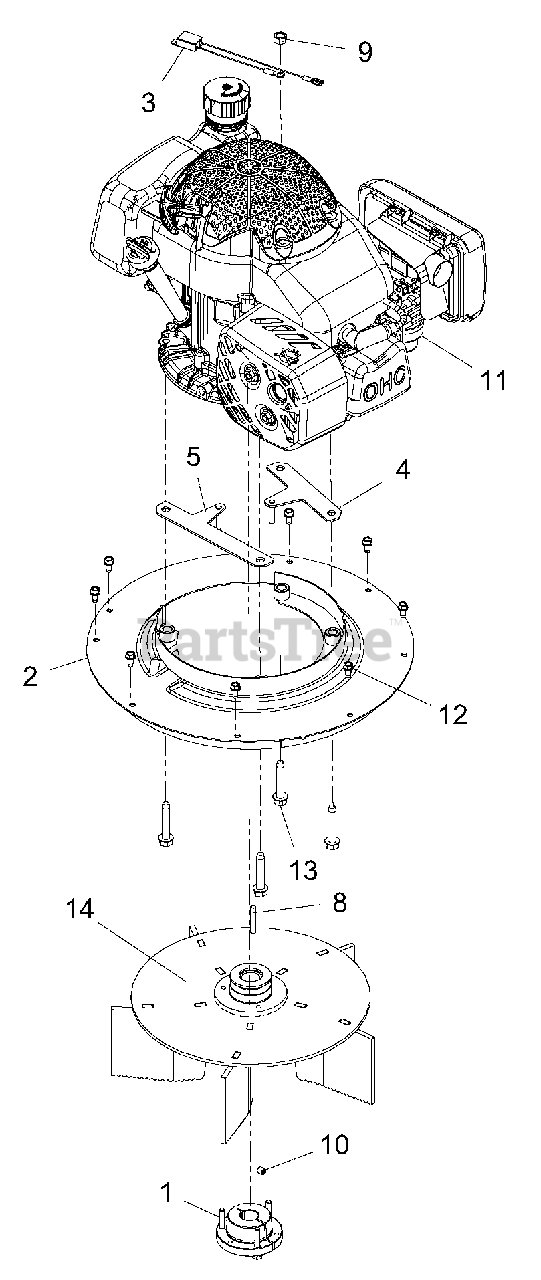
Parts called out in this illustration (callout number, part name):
1	BUSHING, TAPER-SPLIT 7/8"(SDS)
2	WMT-ENGINE PLATE
2	@WSHR-LK .25X.062 REG YWZC
2	BLT-HEX .25-20X1.5 FTHD GR5 ZC
3	WIRE HARNESS-APV
4	WLDMT, BRKT - APV BELT FNGR L
5	WLDMT, BRKT - APV BELT FNGR R
8	KEY-SQ .188X1.50X.188
9	@NUT-LK-CTR .38-16 YWZC
10	SCR-SET .31-18X.38 SKHCUPDL
11	ENGINE-SUBARU EA190V CE
12	SCR-TAP .25-20X.50 HWH TR YWZ
13	SCR-TAP .38-16X2.00 HWH TR YZ
14	WLDMT,IMPELLER - APV TAPER
